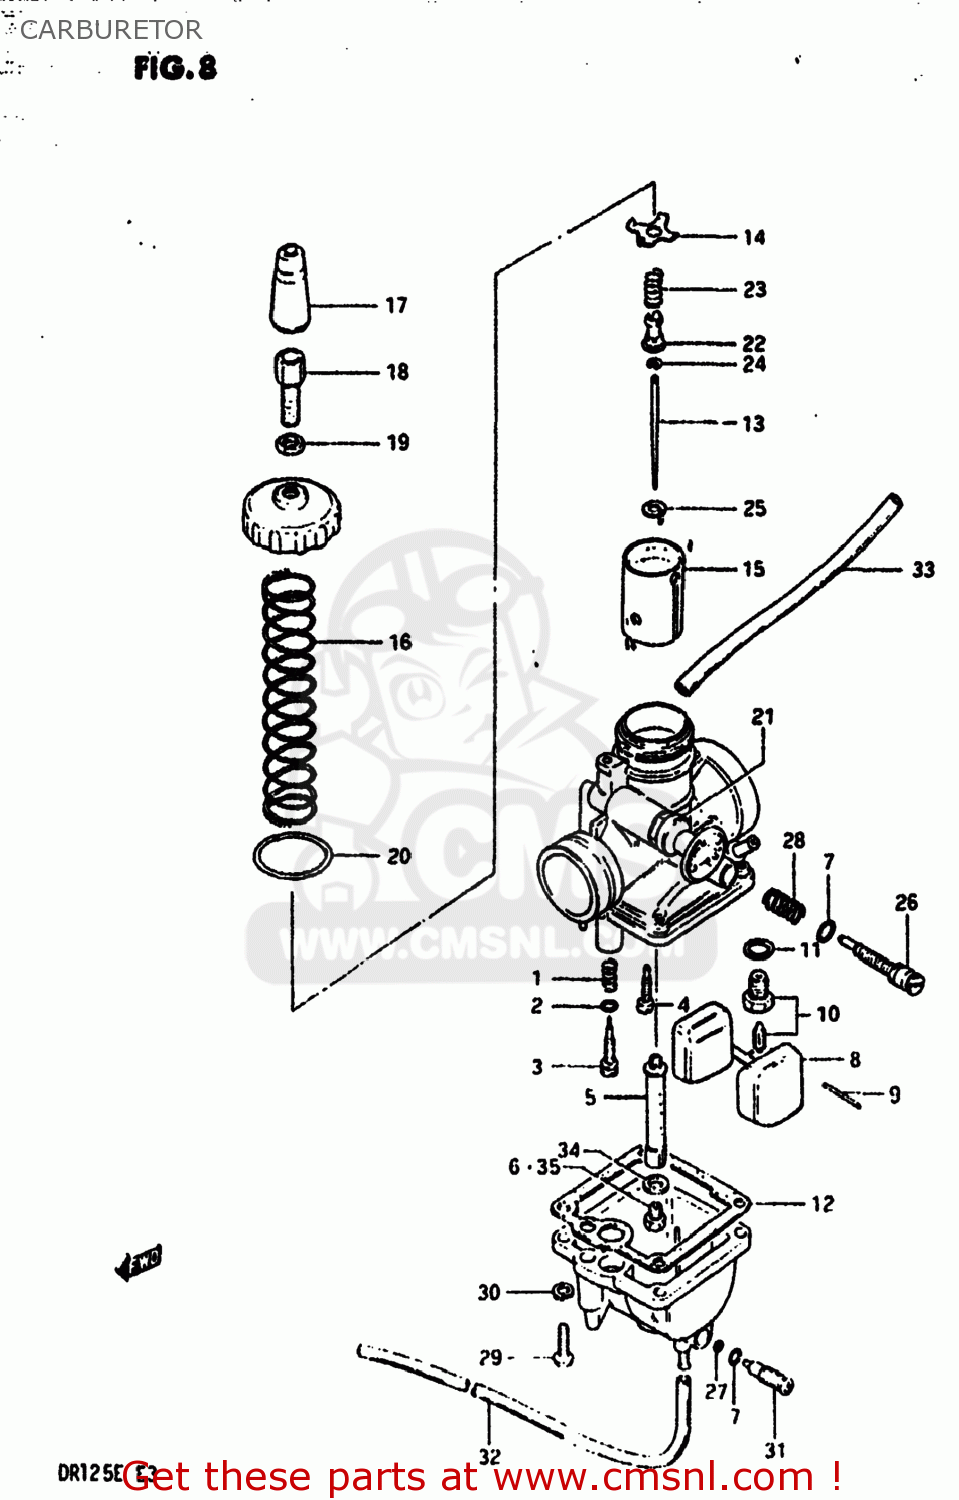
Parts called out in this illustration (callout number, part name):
1	SPRING,THROTTLE ADJUST
2	O-RING
3	SCREW,PILOT AIR
4	JET,PILOT
5	JET,NEEDLE
6	JET,MAIN (98)
7	O-RING
8	FLOAT
9	PIN,FLOAT
10	VALVE ASSY,NEEDLE(ID:2.0)
11	GASKET,NEEDLE VALVE SE
12	GASKET,FLOAT CHAMBER (NAS)
13	NEEDLE JET
14	PLATE,THROTTLE VALVE
15	VALVE,THROTTLE
16	SPRING,THROTTLE VALVE
17	CAP
18	ADJUSTER,CABLE
19	NUT,CABLE ADJUSTER LOCK
20	O-RING,MIXING CHAMBER
21	VALVE ASSEMBLY,STARTER
22	HOLDER,NEEDLE
23	SPRING,NEEDLE JET
24	E-RING
25	RECEIVER,NEEDLE
26	SCREW,THROTTLE STOP
27	O-RING,DRAIN PLUG
28	SPRING,THROTTLE SCREW
29	SCREW
30	LOCK WASHER
31	PLUG,DRAIN
32	HOSE
33	HOSE
34	WASHER,MAIN JET
35	JET,MAIN
